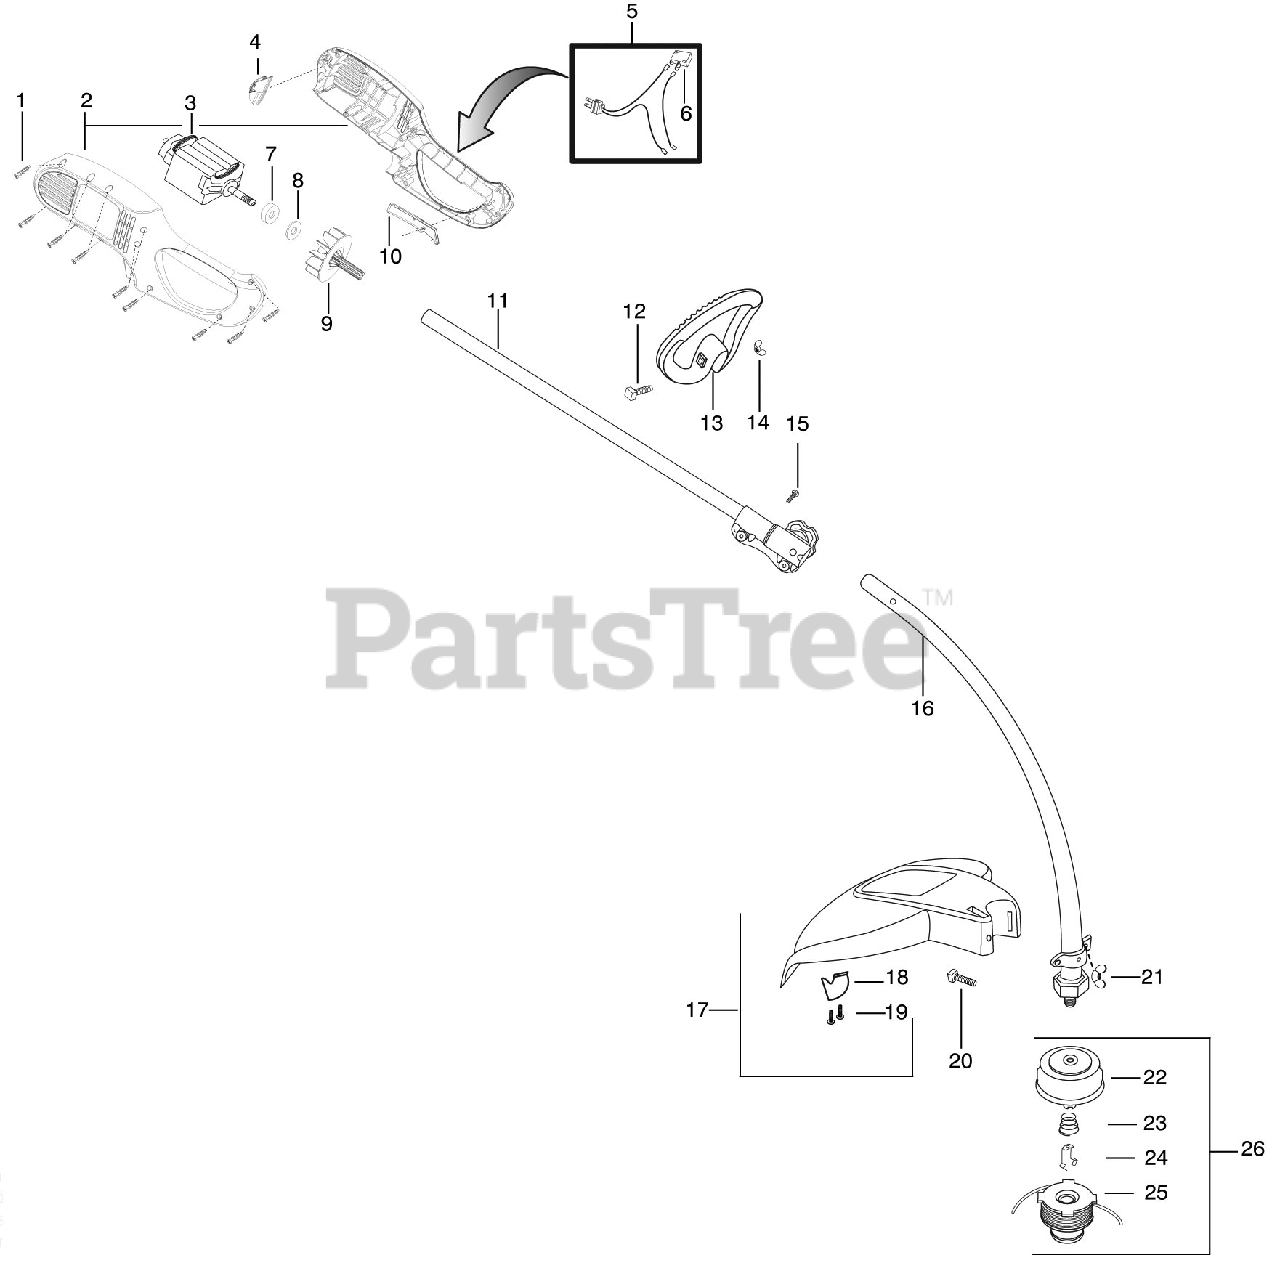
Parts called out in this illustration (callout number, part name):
1	Screw (Qty. 12)
2	Assy-Housing Set w/decal
3	Assy-Motor
4	Retainer-Cord
5	Assy-Wire Harness
6	Switch-Momentary
9	Fan-Cooling
10	Trigger-Switch
11	Kit-Upper shaft w/decal
12	Bolt-Handle
13	Assy-Handle
14	Wing nut
16	Kit-Lower Shaft
17	Kit-Shield
18	Limiter-Line
21	Wingnut
22	Assy-Hub w/arbor
23	Spring-Return
24	Retainer-Spool
25	Accy-Wound Spool
26	Accy-TNG VI Head
